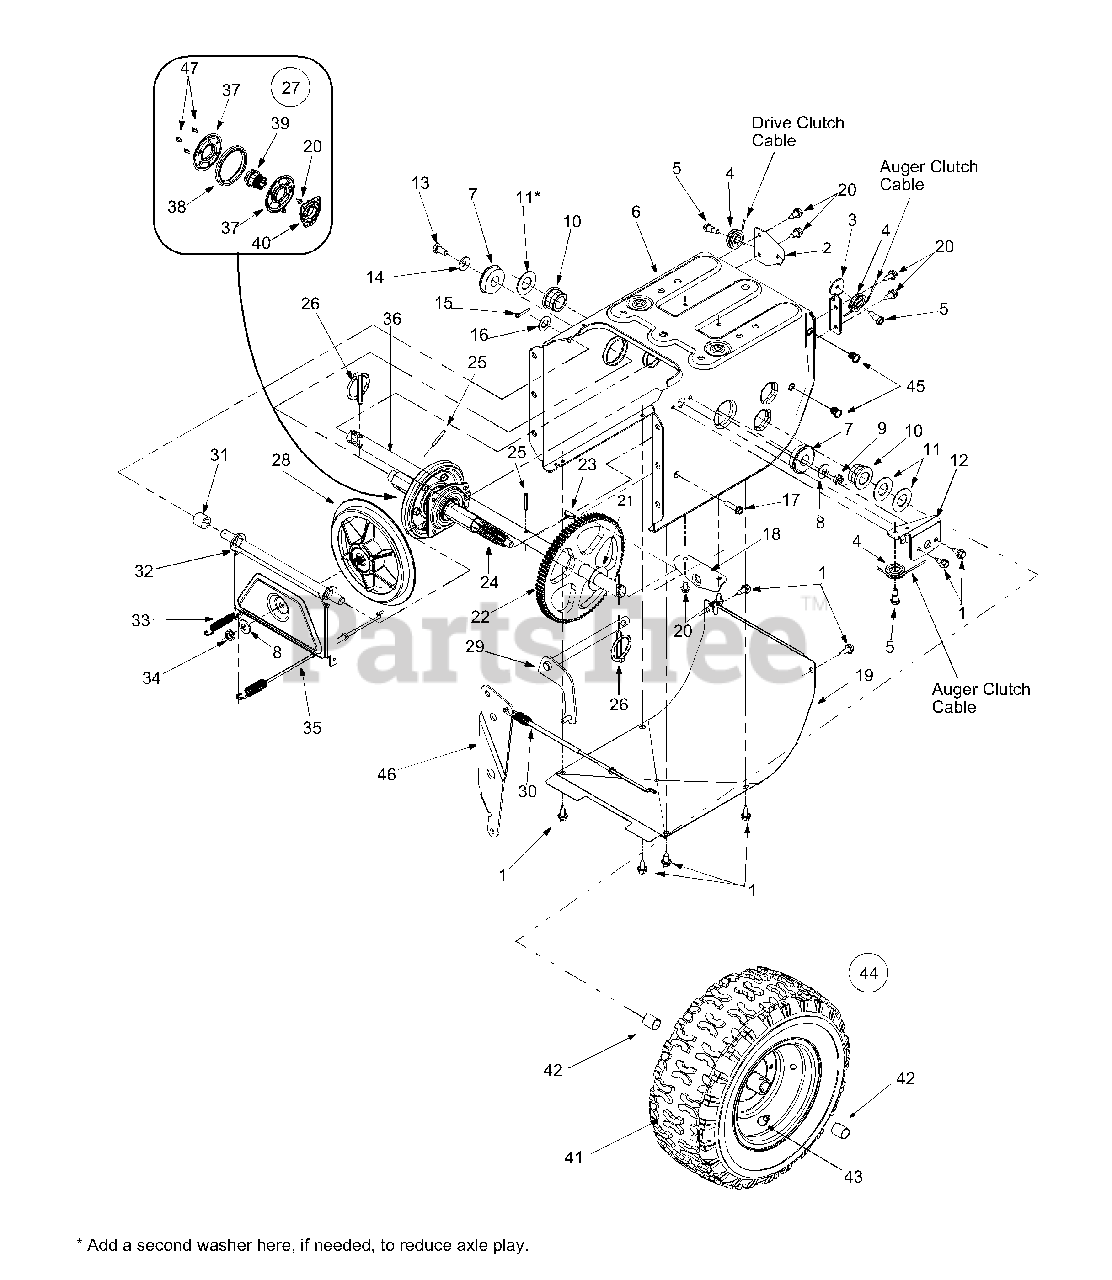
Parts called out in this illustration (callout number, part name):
1	Hex Screw 1/4-20 x .625
5	Shoulder Screw 1/4-28 x .375
9	Lock Jam Nut, 3/8-24
10	Hex Flange Bearing
11	Flat Washer, .76 x 1.49 x .06
14	Bell Washer .340 ID x .872 OD
15	Cotter Pin, .125 x .75
16	Flat Washer .536 ID x .930 OD
17	Hex Washer Screw 1/4-20
21	Flat Washer .760 ID x .50 OD
22	Gear, 80-tooth
23	Key, 3/16 x 3/4
24	7-Tooth Shaft
25	Roll Pin
26	Clik Pin
27	Friction Wheel Assembly
28	Friction Wheel Disc
29	Wheel Shift Rod Assembly
30	Drive Cable
34	Jam Nut, 3/8-24
35	Drive Cable
36	Wheel Axle, .750 x 22.21
37	Friction Wheel Side Plate
38	Friction Wheel Rubber
39	Friction Wheel Hub
40	Friction Wheel Bearing
42	Sleeve Bearing, .75 x .87 x 1
43	Air Valve
47	Hex Washer Screw 1/4-20
